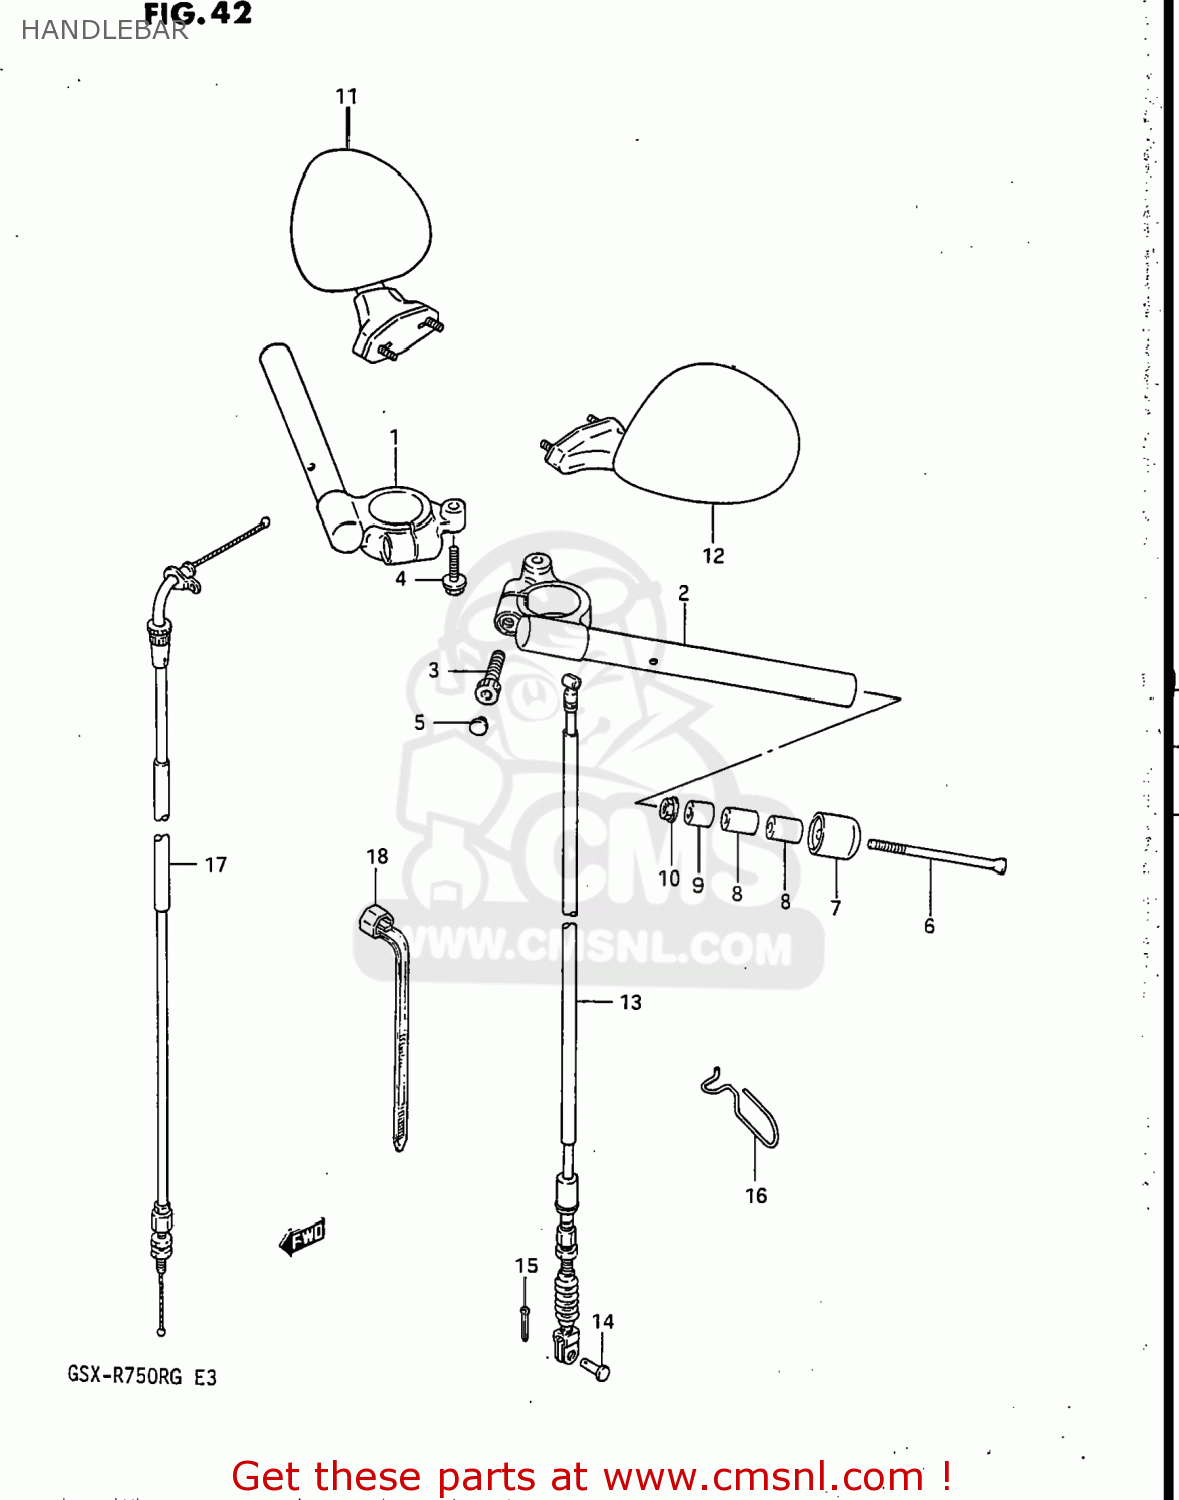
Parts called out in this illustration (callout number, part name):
1	HANDLEBAR,RIGHT
2	HANDLEBAR,LEFT
3	BOLT 8X35
4	BOLT
5	CAP(OD:10)
6	SCREW(6X85)
7	CAP,BALANCER
8	BALANCER,HANDLEBAR INNER
9	EXPANDER,HANDLE BALANCER
10	NUT
11	MIRROR ASSEMBLY,RIGHT
12	MIRROR ASSEMBLY,LEFT
13	CABLE ASSY,CLUTCH
14	PIN(L:15)
15	PIN
16	CLAMP,CABLE
17	CABLE ASSY,THROTTLE
18	CLAMP(L:165)
